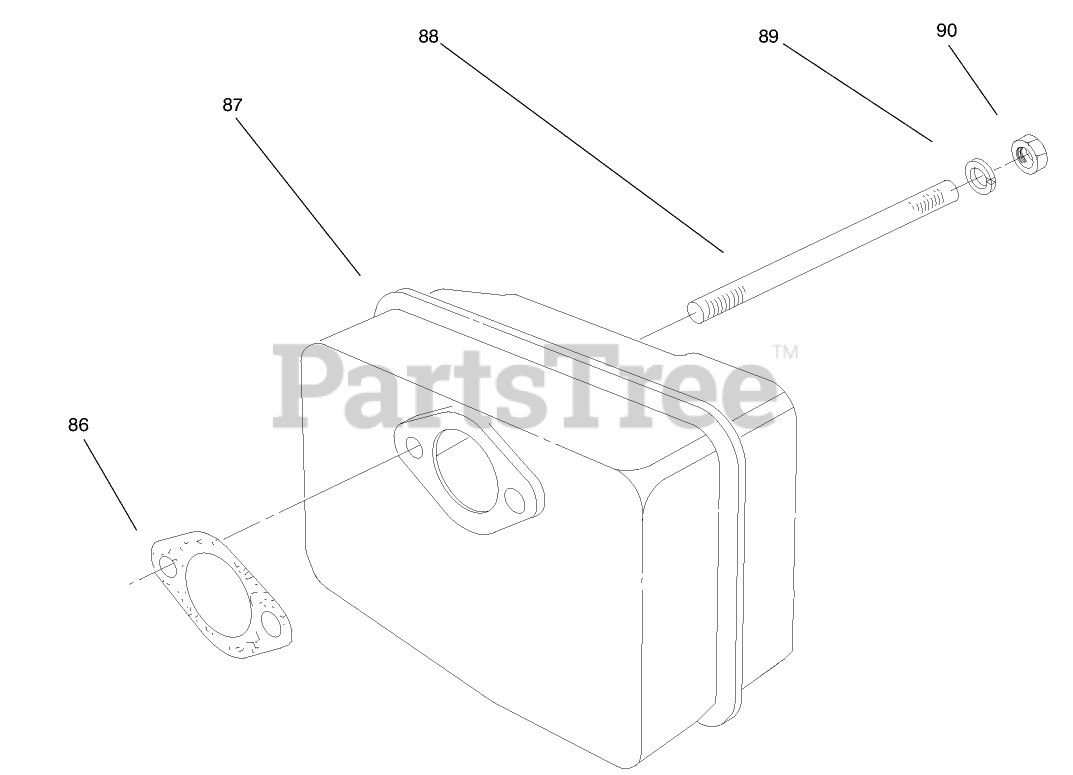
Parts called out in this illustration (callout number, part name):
86	GASKET
87	MUFFLER
89	WASHER-LOCK
